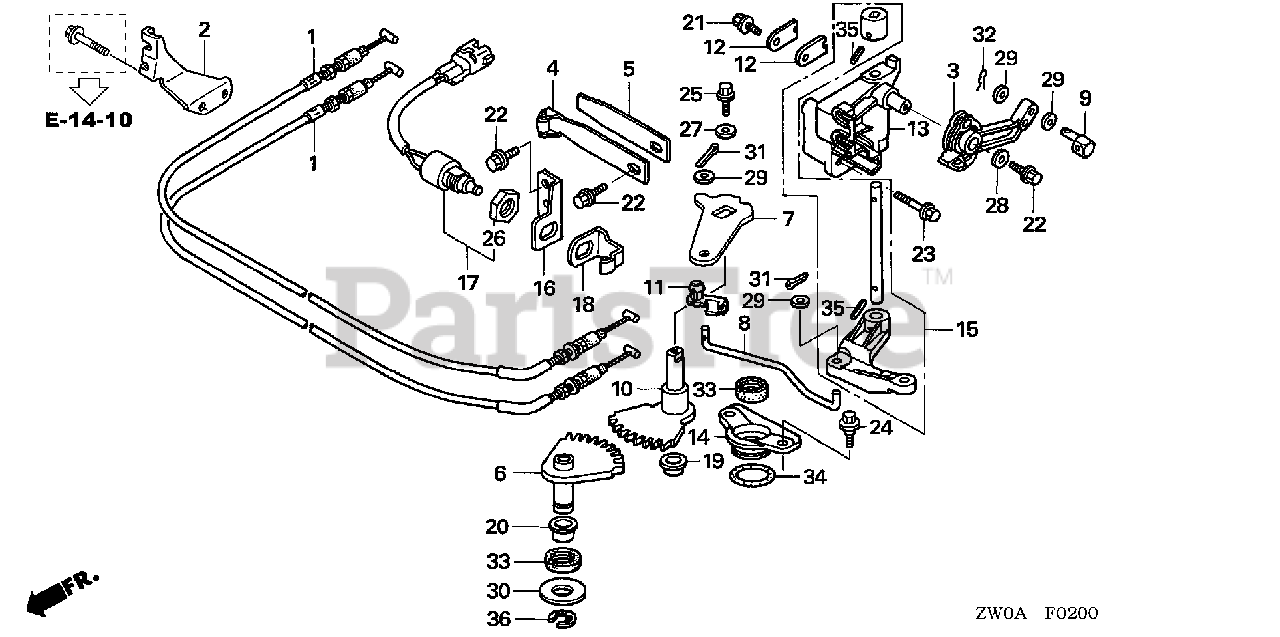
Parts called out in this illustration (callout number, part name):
1	CABLE, THROTTLE
2	STAY, THROTTLE CABLE
3	ARM, THROTTLE
4	SPRING, CLICK
5	SPRING, CLICK ASSIST
6	SHAFT, SHIFT (A)
7	ARM, SHIFT
8	ROD, LINK
9	PIVOT, SHIFT
10	SHAFT, SHIFT (B)
11	BUSH, SHAFT
12	PLATE, SHIFT SHAFT
13	BRACKET, SHIFT LINK
13	BRACKET, SHIFT LINK *NH8* (DARK GRAY)
14	HOLDER, SEAL
15	LINK, SHIFT
16	BRACKET, NEUTRAL SWITCH
17	SWITCH ASSY., NEUTRAL
18	PLATE, NEUTRAL SWITCH
19	BUSH, TORQUE LINK
20	BUSH (14X10)
21	BOLT, FLANGE (6X14) (CT200)
22	BOLT, FLANGE (6X12)
23	BOLT, FLANGE (6X35)
24	BOLT, FLANGE (6X11)
25	BOLT, FLANGE (6X12)
26	NUT, HEX. (20MM)
27	WASHER (6MM)
28	WASHER, PLAIN (6MM)
29	WASHER, PLAIN (6MM)
31	PIN, SPLIT (2.0)
32	PIN, LOCK SPECIAL (6MM)
33	SEAL, WATER (14X26X6)
34	O-RING (27X2) (ARAI)
35	PIN, SPRING (3X18)
36	E-RING (12MM)
